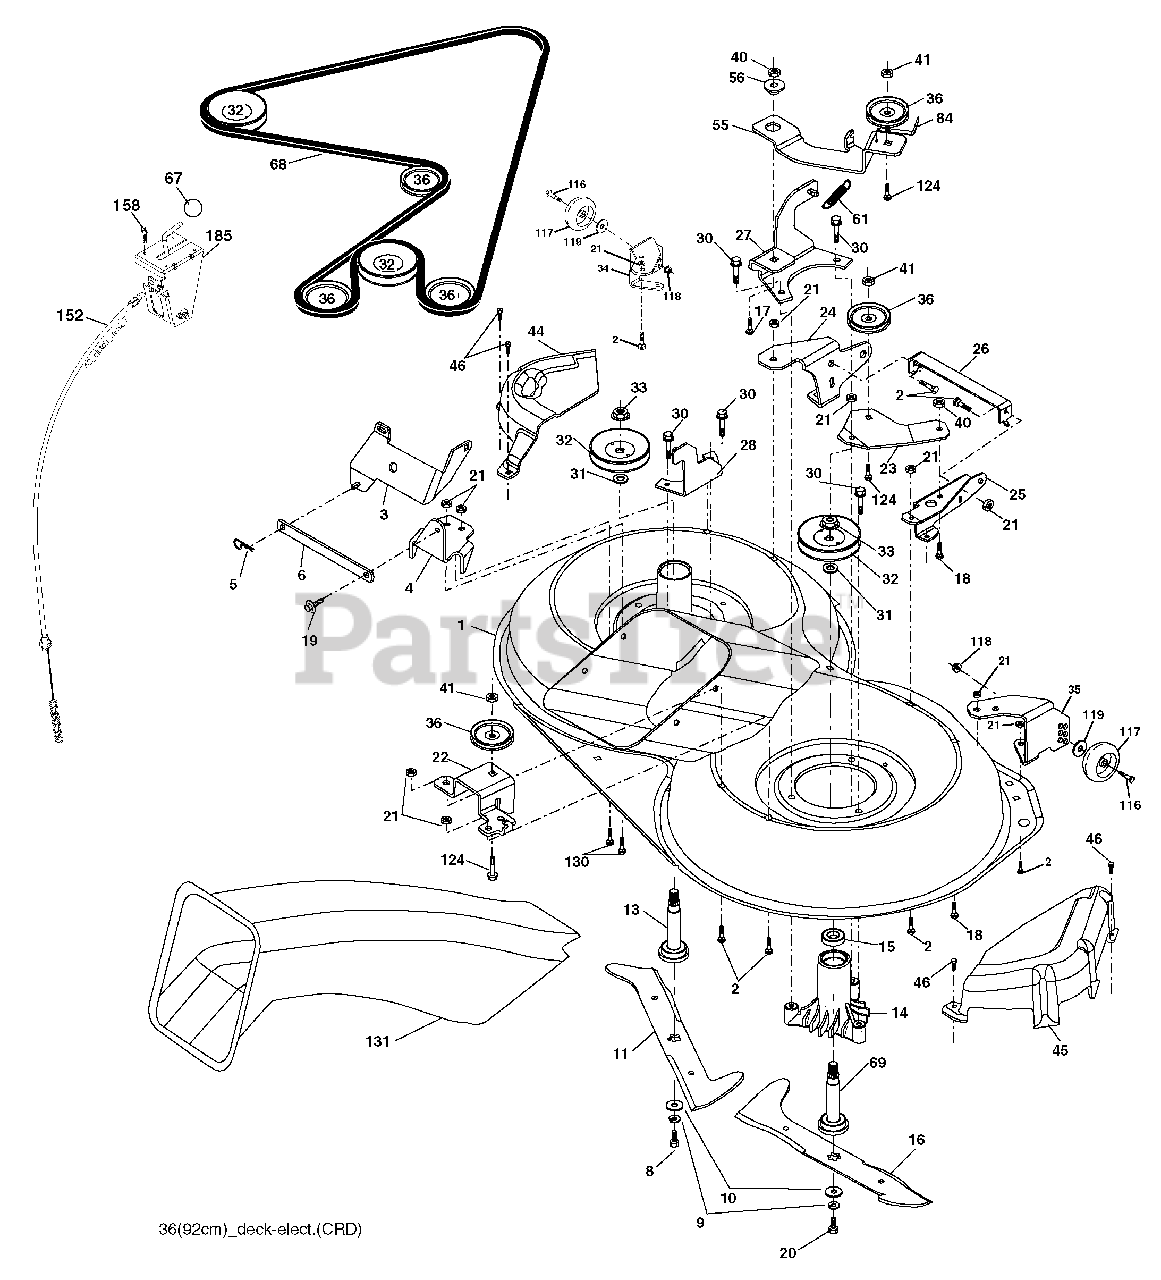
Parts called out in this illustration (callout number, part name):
1	Housing Asm. Mower
2	Bolt Rdhd Sqnk 5/16-18 unc x 3/4
3	Bracket Asm. S-Bar Chass
4	Bracket Bar Sway Deck
5	Retainer Spring
6	Bar Sway
8	Bolt 3/8-24 x 1.25 Gr. 8 Patched
9	Washer Lock Hvy 3/8 Unplated
13	Shaft Asm. W/Lower Bearing
14	Housing Mandrel Vented (Machd)
15	Bearing Ball Mandrel
17	Nut Crownlock 3/8-16 unc
18	Bolt Rdhd Sqnk 3/8-16 x 3/4 Gr. 5
19	Bolt Shoulder 5/16-18 Thd Form
20	Bolt 3/8-24 x 1.25 Gr. 8 Ptch
21	Nut Crown Lock 5/16-18
22	Bracket Idler Sprt RR
23	Bracket Idler Sprt RF
24	Bracket Suspension LF
25	Bracket Suspension RF
26	Brace Support Susp Frt CRD
27	Bracket Asm. Susp RR
28	Bracket Asm. Susp LR
30	Screw Thd Rolling Dod.PT Hex
31	Washer Spacer Mower Vented
32	Mandrel Pulleys
33	Nut Flg Top Lock
34	Bracket Gauge Wheel Lf
35	Bracket Gauge Wheel Rf
36	Pulley Idler V-Groove Dim 4.25
40	Nut Crownlock 3/8-16 unc
41	Nut Flangelock 3/8-16 unc
44	Cover Mandrel Lh
45	Cover Mandrel Rh
46	Screw Thd Roll 1/4-20 x 5/8
55	Arm Idler
56	Spacer Retainer
61	Spring Tension Belt
68	Hex-Belt Mower
69	Shaft Asm W/Lwr Brg Rh Thd
84	Keeper Belt Idler
116	Bolt Shoulder
117	Wheel Gage
118	Nut Centerlock 3/8-16 unc
119	Washer 3/8 x 7/8 x 14 Ga.
124	Bolt Carr Sh 3/8-16 x 1-1/2 Gr5
130	Bolt Rdhdsqnk 5/16-18 unc x 3/4
131	Chute Bagger CRD 92cm
158	Screw 1/4-20 x 1/2
185	Head Asm Cable Clutch
185	Mandrel Asm Service
185	Mandrel Asm CRD Lh Threads VC
185	Replacement Mower Complete
